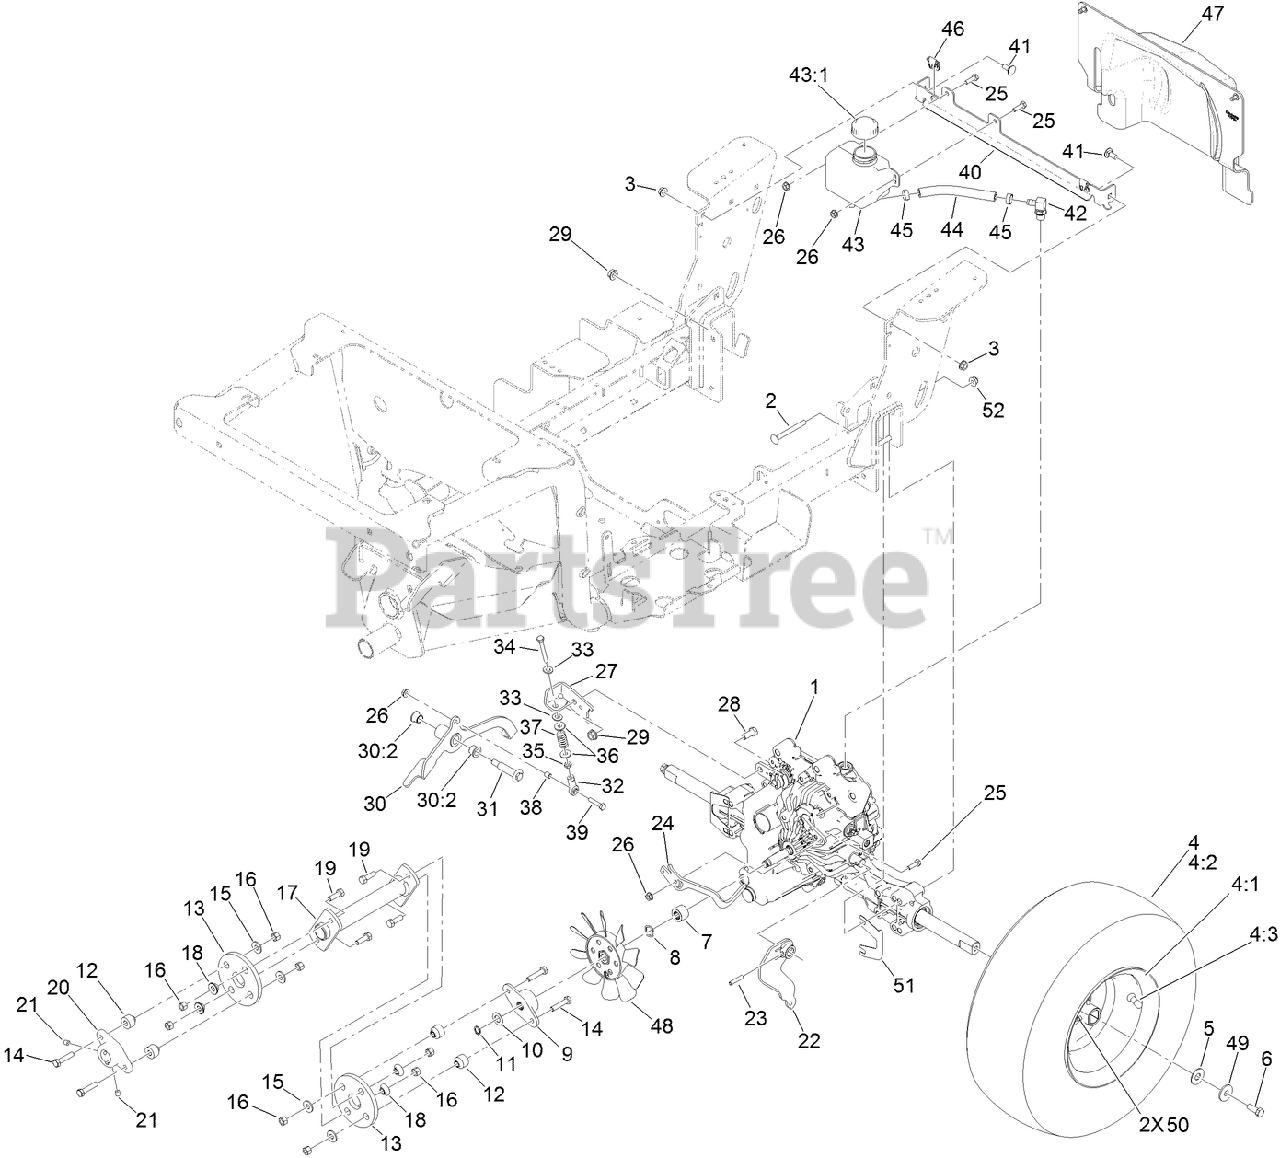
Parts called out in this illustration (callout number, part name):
1	TRANSAXLE
2	SCREW-CARR
3	NUT-HF
4	WHEEL AND TIRE ASM
4:3	STEM-VALVE
5	WASHER-NYLON
6	SCREW-HH, LOCK
7	SPACER-SHAFT, INPUT
8	WASHER-SPRING
9	HUB-SHAFT, TRANSAXLE
10	SPACER
11	RING-RETAINING
12	SPACER-COUPLING, RUBBER
13	COUPLING-RUBBER
14	SCREW-HH
15	WASHER-FLAT
16	NUT-HEX
17	SHAFT-DRIVE
18	SPACER-COUPLER, RUBBER
19	SCREW-HH
20	HUB-SHAFT, ENGINE
21	SETSCREW
22	ARM-MOTION
23	PIN-SPIRAL
24	ARM-RELEASE
25	SCREW-HH
26	NUT-HF
27	ARM-BRAKE
28	SCREW-HH
29	NUT-HF
30	BRAKE LEVER ASM
30:2	BEARING-FLANGE
31	BOLT-SHOULDER
32	ROD END-BALL JOINT
33	WASHER-SPRING
34	SCREW-HH
35	NUT-JAM
36	WASHER-FLAT
37	SPRING-COMPRESSION
38	SPACER
39	SCREW-HH
40	BRACKET-MOUNT, TANK
41	SCREW-CARR
42	FITTING-90 DEG
43	TANK ASM
43:1	CAP-TANK
44	HOSE-EXPANSION
46	RECEPTACLE-CLIP, MINI
47	TRANSAXLE COVER ASM
48	FAN-7 INCH
49	SPACER-WHEEL
50	SCREW-SET, SQH
51	SPACER-TRANSAXLE
52	NUT-HF, NI
